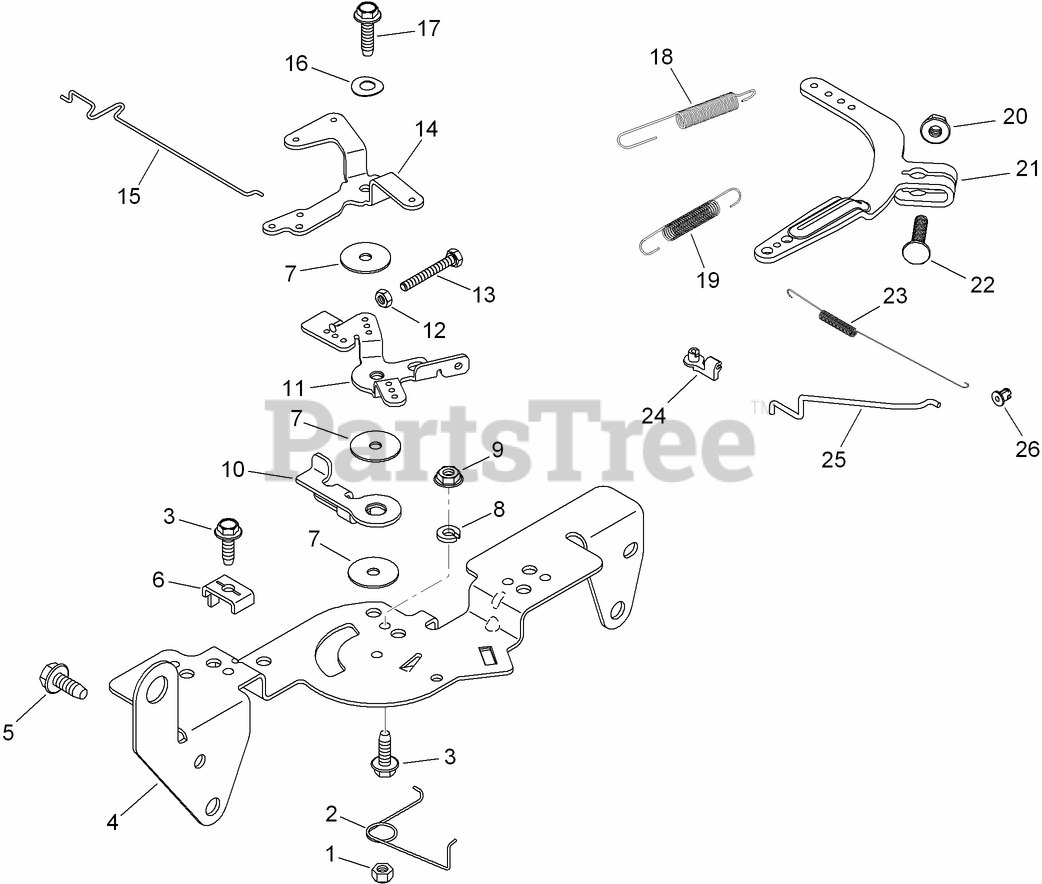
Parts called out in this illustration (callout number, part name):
1	NUT-LOCK (M5X.8)
2	SPRING-RETURN, CHOKE
3	SCREW-FLANGE, THREAD FORMING (M5X0.8X16)
4	Bracket-Control
5	SCREW-FLANGE, THREAD FORMING (M6X1.0X16)
6	CLAMP-CABLE
7	WASHER-FLAT (5.5MM)
8	Washer-Lock (.25)
9	Nut-HF (M5x0.8)
10	Lever-Actuator, Throttle
11	Lever-Control, Throttle
12	NUT (M4X0.7)
13	Screw (M4x0.7x30)
14	LEVER-CHOKE
15	Linkage-Choke
16	WASHER-SPRING (1/4)
17	SCREW-FLANGE, THREAD FORMING (M5X.8X20)
18	Spring-Limiter, Throttle
19	Spring-Governor
20	NUT-FLANGE (M6X1.0)
21	LEVER-GOVERNOR
22	BOLT-SQ NECK, RD HD (M6X1.0X25)
23	SPRING-LINKAGE
24	BUSHING-RETAINING, LINKAGE
25	Linkage-Throttle
26	BUSHING-LINKAGE, THROTTLE
